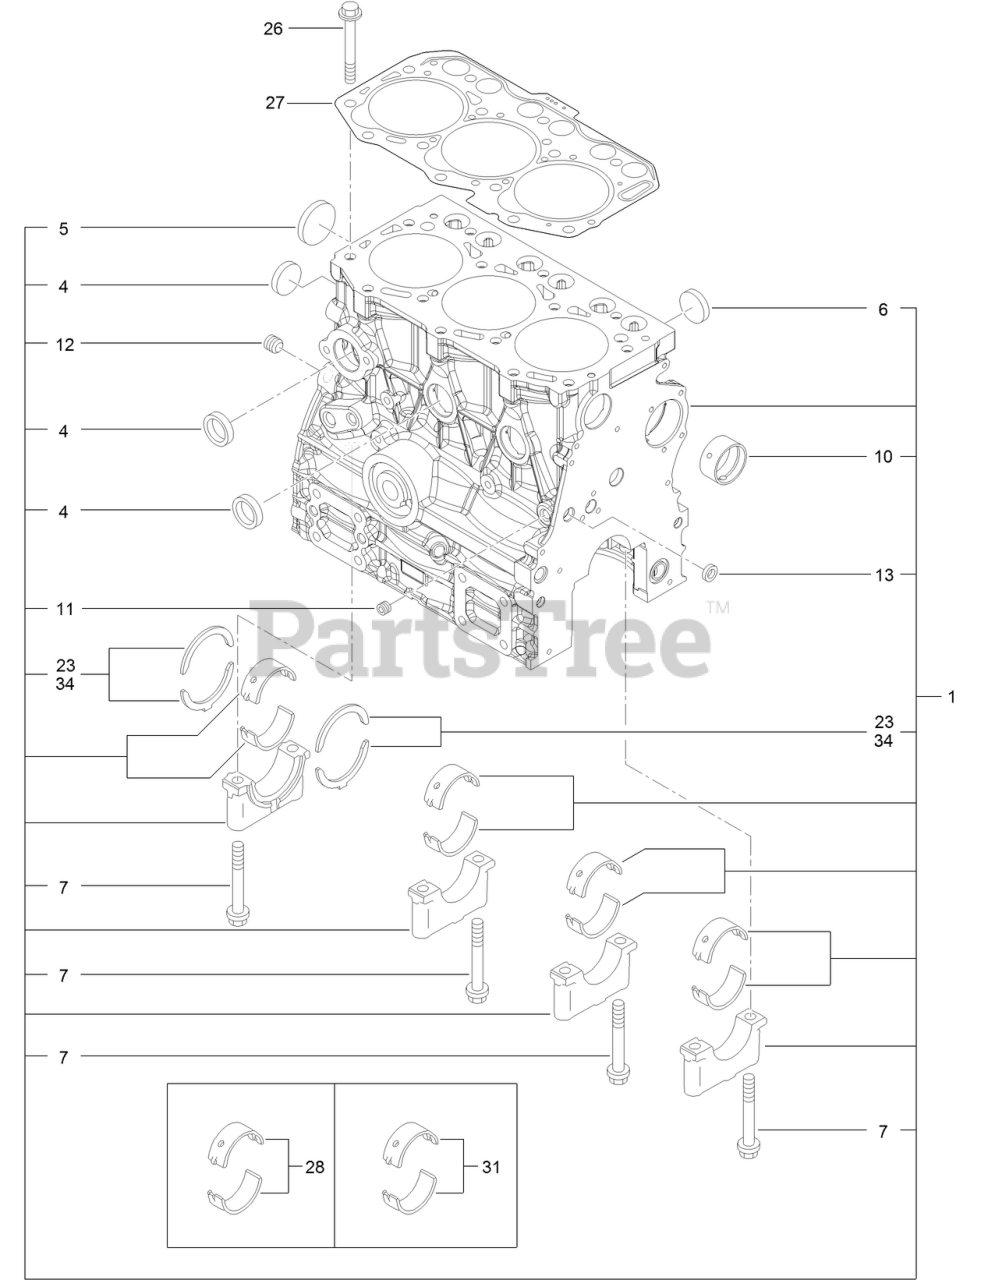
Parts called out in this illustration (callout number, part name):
1	BLOCK ASM-CYLINDER
4	PLUG, CUP TYPE 30
5	PLUG-DISH
6	PLUG-CUP TYPE 25
7	BOLT-METAL CAP
10	BUSH-CAMSHAFT
23	BEARING ASSY-THRUST
26	BOLT, CYLINDER HEAD
27	GASKET SET-HEAD
28	BEARING ASSY-MAIN
31	BEARING ASSY-MAIN
34	BEARING-THRUST
